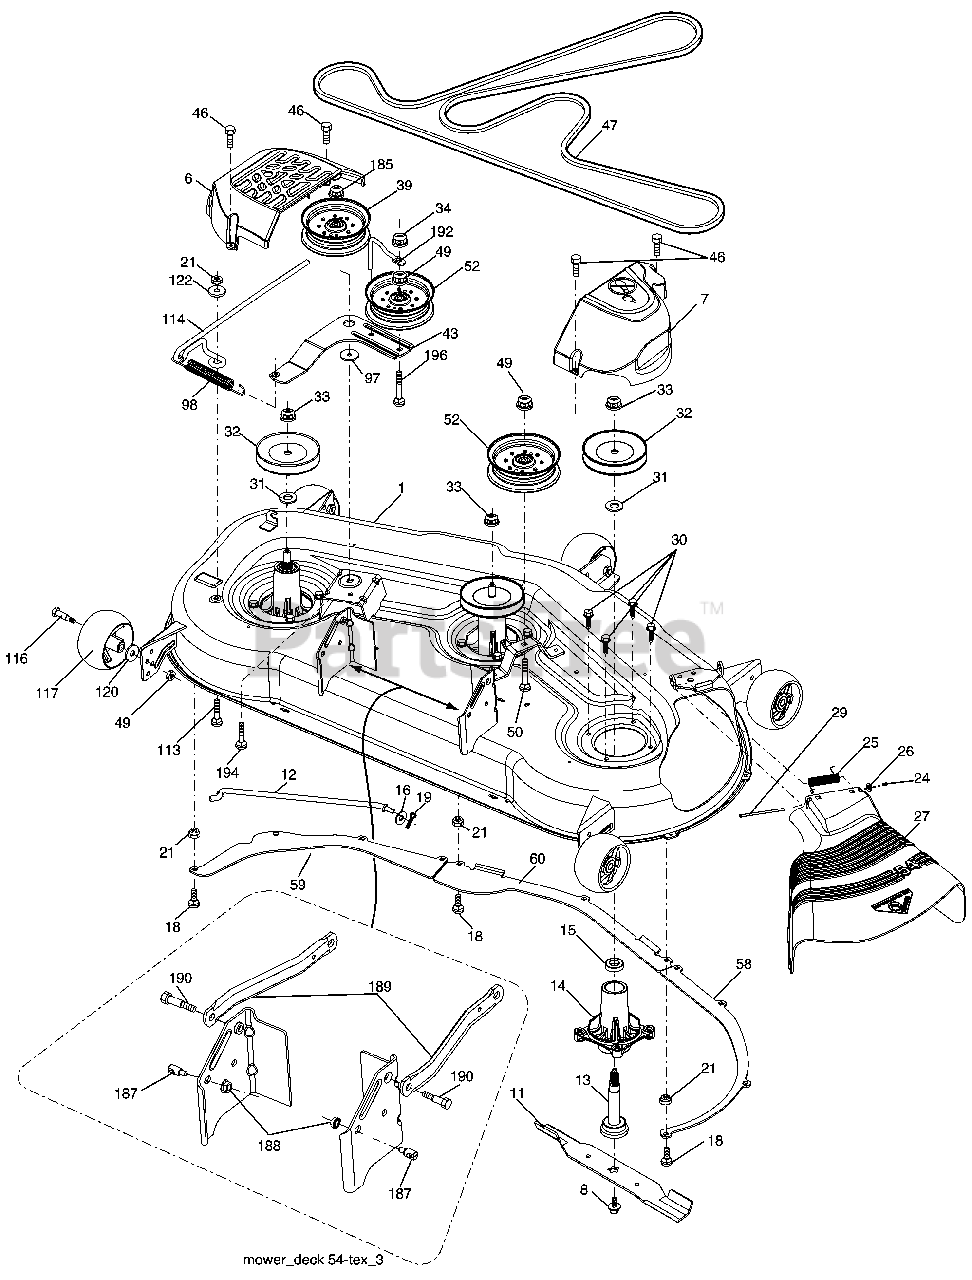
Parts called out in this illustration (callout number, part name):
1	Deck Weldment Mower
6	Cover Mandrel LH
7	Cover Mandrel RH
8	Bolt 7/16 Asm. Blade
11	Blade Bagging
12	Rod Anti Sway
13	Shaft Asm. w/Lower Bearing
14	Housing, Mandrel
15	Bearing, Ball, Mandrel
16	Washer 13/32 x 13/16 x 12 Ga.
18	Bolt Rdhd Sqnk 5/16-18 x 5/8
19	Pin cotter 5/16 Bowtie Lock
21	Nut, Crownlock 5/16-18 unc
24	Cap Sleeve
25	Spring, Torsion
27	Defl ector Shield
29	Rod, Hinge
30	Screw, Thdroll Washer Head
31	Washer, Spacer Mower Vented
32	Pulley, Mandrel
33	Nut, Flg. Top Lock
34	Nut Crownlock 3/8-16 unc
39	Pulley, Idler, Stationary LH
43	Arm, Idler
46	Screw, Thdroll. 1/4-20 x 5/8
47	Belt Deck Drive
49	Nut, Lock Flg. 3/8-16 unc
50	Bolt Rdhd Sqnk 3/8-16 unc x 2
52	Pulley Idler
58	Baffl e Right
59	Baffl e Left
60	Baffl e Center
97	Washer Hardened
98	Spring Drive
113	Bolt Rdhd Sqnk 5/16-18 x 3/4
114	Rod Tension Relief
116	Bolt, Shoulder
117	Gauge Wheel
120	Washer 13/32 x 1-1/4 x 12 Ga.
122	Bushing Tension Relief
185	Nut Lock Flange 7/16-14 Gr. 5
187	Stud Fastener w/"D" Anti-Rotation
188	Nut Lock Hex Flange
189	Arm Susp. Mower Rear
190	Bolt Shoulder
192	Keeper Belt Idler
194	Bolt Carr Sqnk 7/16-18 x 2
196	Bolt Rdhd Sqnk 3/8-16 x 2-1/2 Gr. 5
